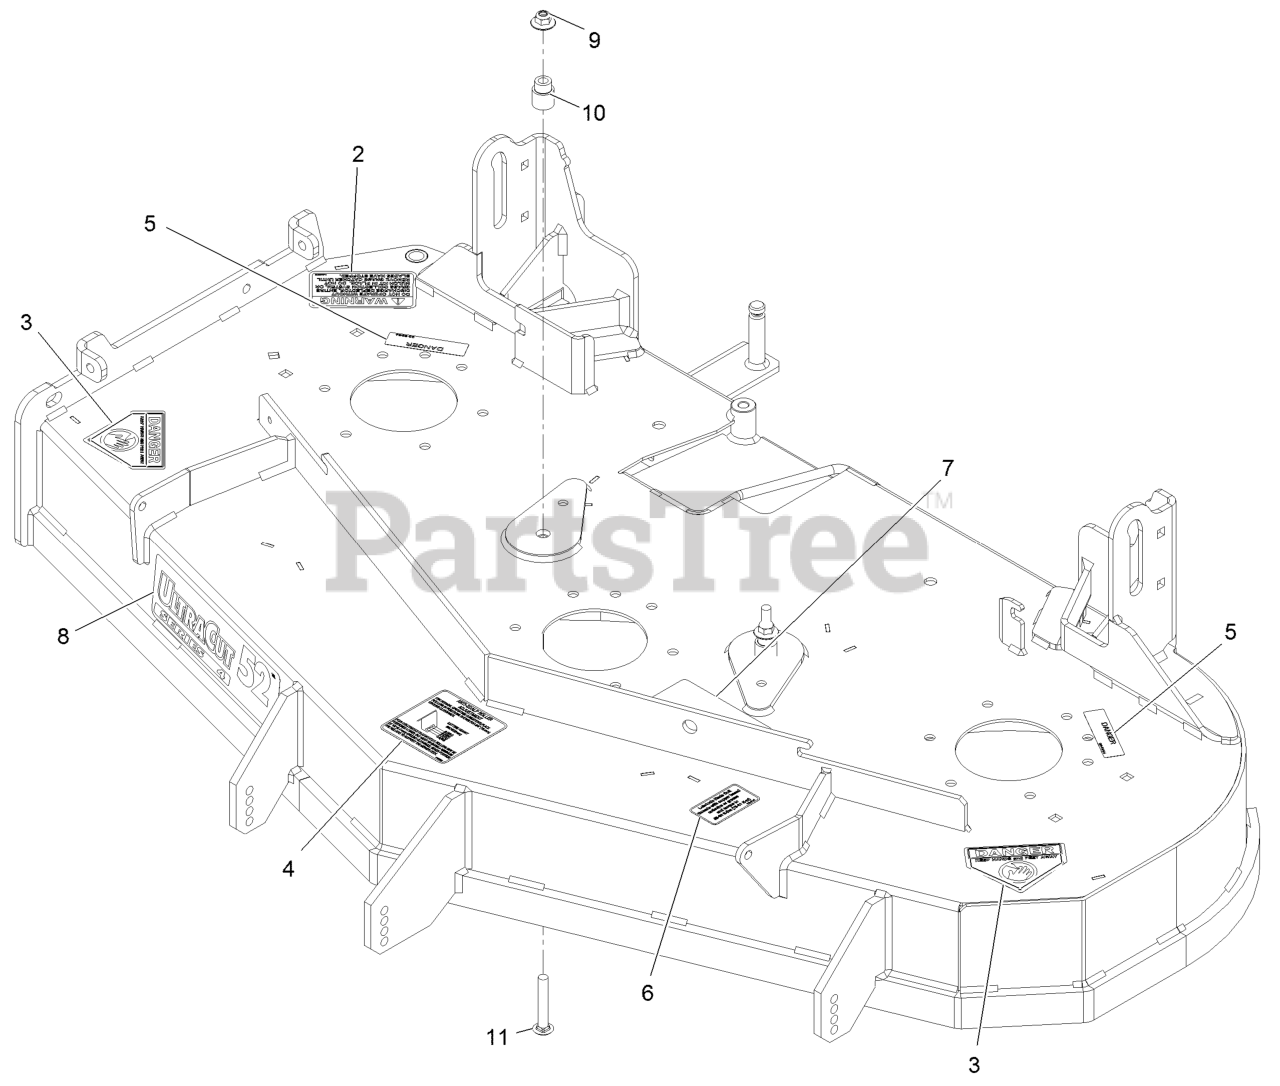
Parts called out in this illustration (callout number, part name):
2	DECAL-WARNING, DISCHARGE
3	DECAL-DANGER
4	DECAL,ANTISCALP
5	DECAL-COVER, MISSING
6	DECAL,BOLT TORQUE
7	DECAL,BELT ROUTING
8	DECAL,ULTRACUT 52 SERIES
9	Nut-Nyloc 3/8-16 Flg
10	BUSHING-IDLER
11	SCREW-CARR
